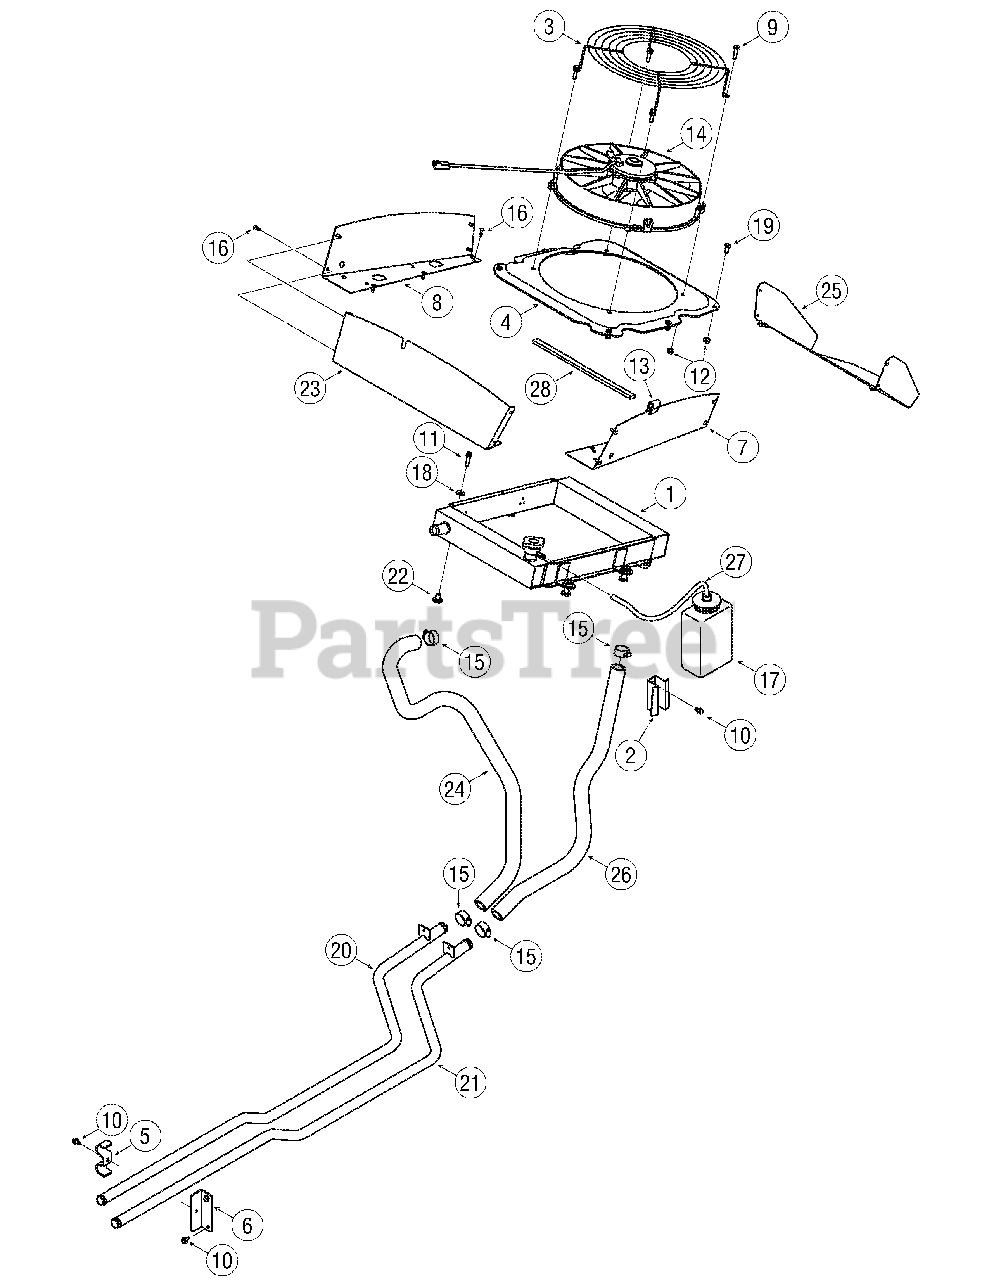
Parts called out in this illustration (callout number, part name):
1	Radiator Asm, zin Core
3	Guard, fan
4	Shrd, Fan, Mount
9	Hhcs, 1/4-20, 1.00, gr5
10	Scr, tt, 1/4-20, 0.500, hxindwsh
11	Scr, tt, 1/4-20, 1.000, hxindwsh
12	Nut, flglk, 1/4-20, grf, nylon
13	Heat Baffle Seal
14	Fan, electric, 12v
15	Clamp, hose, adj
16	Pop Rivet 3/16 Dia x .450, sty1
17	Cntnr, over Flow, coolant
18	Wash, flat, .28 x .74 x .063
19	Scr., 1/4-20 x .620
22	Spcr, Step
24	Hose, rdtr, frt 4x4
26	Hose, rdtr, frt 4x4
27	Tube, overflow, rdtr
28	Tape, .625 Wide x .25 Thk Foam
